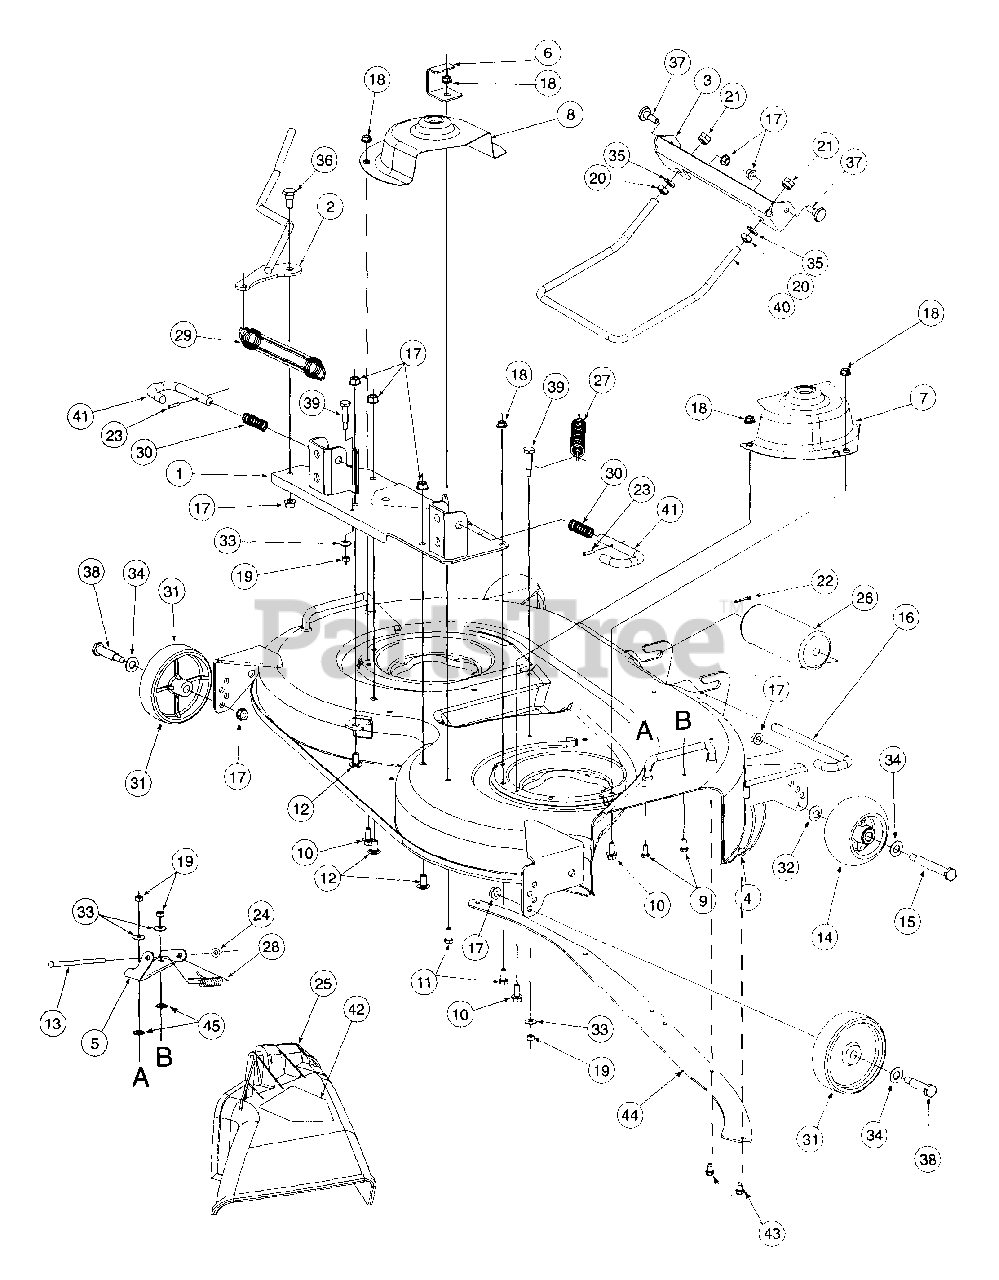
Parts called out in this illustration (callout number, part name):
1	Plate Assembly, Mounting
3	Bracket, Front Lift
4	Deck Assembly
5	Bracket, Hinge Mounting
6	Bracket, Handle Stop
7	Shield, RH Pulley
9	Screw, Hex Cap, 1/4-20 x .62 GR5
10	Screw, Hx Wsh Hd Tapp, 5/16-18 x .75
11	Screw, Hex Cap, 5/16-18 x .75 GR5
12	Bolt, Carriage, 3/8-16 x .75
13	Pin, Hinge, .25 Dia x 6.75 Lg
14	Wheel, Deck w/Fitting
15	Bolt, Shoulder, 1/2 x 2.5
16	Pin, Roller, 1/2 Dia x 7.31 Lg
17	Nut, Hex Flange Lock, 3/8-16
18	Nut, Hex Flange Lock, 5/16-18 GR5
19	Nut, Hex, 1/4-20
20	Nut, Hex Jam, 1/2-13 GR5
21	Nut, Hex Insert Lock, 1/2-13
22	Pin, Cotter, 3/32 x 1.25
23	Pin, Spiral Spring, 3/16 x .75
24	Cap, Speed Nut
25	Deflector Assy
27	Spring, Extension, .88 OD x 6.12
28	Spring, Torsion
29	Spring, Extension, 1.25 OD x 8.15
30	Spring, Compression
31	Wheel, Deck, 5 in. Dia
32	Washer, Bell, .401 x .870 x .063
33	Washer, Bell, .265 x .75 x .062
34	Washer, Flat, .510 x 1.0 x .060
35	Washer, Lock, 1/2
36	Bolt, Shoulder, .498 Dia x .340 Lg
37	Bolt, Shoulder, .50 Dia x .434 Lg
38	Bolt, Shoulder, .498 Dia x 1.64 Lg
39	Bolt, Shoulder, .375 Dia x 1.16 Lg
40	Rod, Front Lift
41	Pin, Mower Support
42	Graphic, Danger
43	Screw, Self Tapping, 1/4-20 x .5
45	Nut, Push, 1/4
